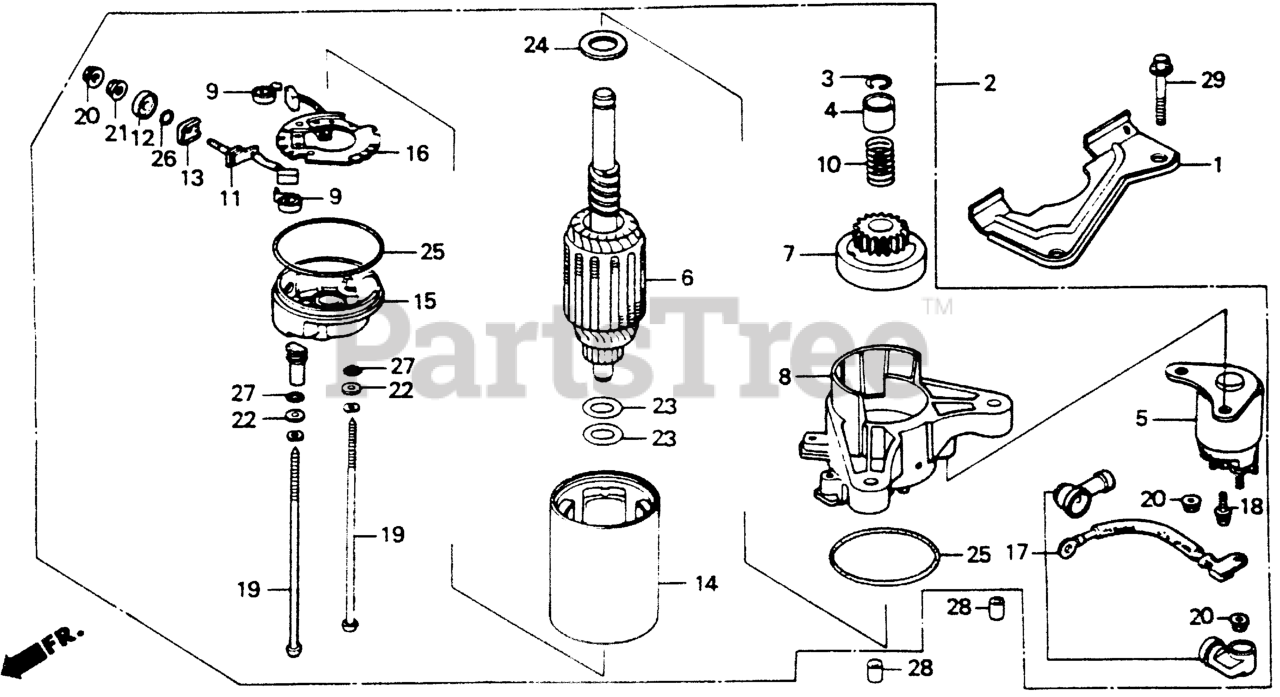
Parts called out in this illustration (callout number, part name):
1	PLATE, SIDE
2	MOTOR ASSY., STARTER
3	RING, SNAP
4	COLLAR, CLUTCH
5	CONTACTOR ASSY.
6	ARMATURE
7	CLUTCH, OVERRUNNING
8	HOUSING, DRIVE SIDE
9	SPRING, BRUSH
10	SPRING
11	BRUSH
12	BUSHING, INSULATION
13	BUSHING, INSULATION
14	YOKE
15	FRAME, STARTER END
16	PLATE, BRUSH HOLDER
17	WIRE, WATER COVER
18	SCREW-WASHER (5X14)
19	BOLT, THROUGH (Honda Code 1412428). (NOT AVAILABLE)
20	NUT
21	NUT
22	WASHER, STEEL PLATE
23	WASHER
24	WASHER
26	O-RING
27	O-RING
28	PIN A, DOWEL (10X16)
29	BOLT, FLANGE (8X35)
